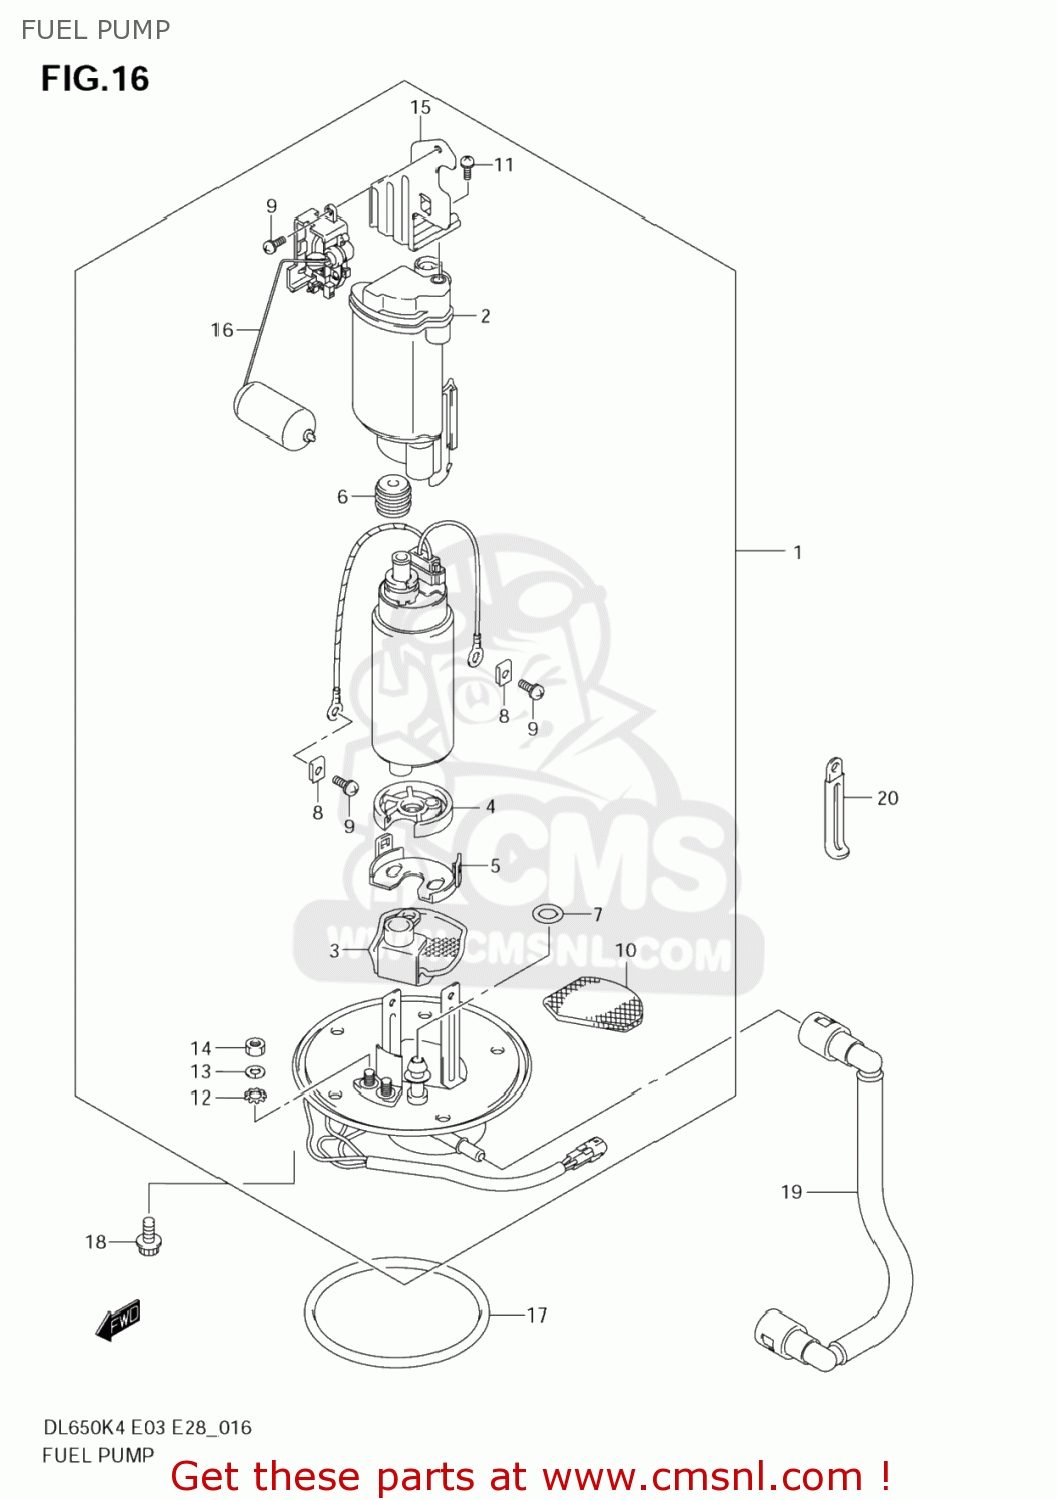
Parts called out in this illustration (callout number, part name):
1	PUMP ASSY,FUEL
2	FILTER,FUEL
3	STRAINER,FUEL PUMP
4	CUSHION
5	HOLDER,FUEL PUMP
6	BUSH,FUEL PUMP
7	O RING
8	NUT
9	SCREW
10	SHEET
11	SCREW
12	WASHER
13	WASHER,SPRING
14	NUT
15	BRACKET,FUEL GAUGE
16	GAUGE ASSY,FUEL LEVER
17	O RING,FUEL PUMP
18	BOLT
19	HOSE COMP,FUEL
20	CLAMP(L:45)
